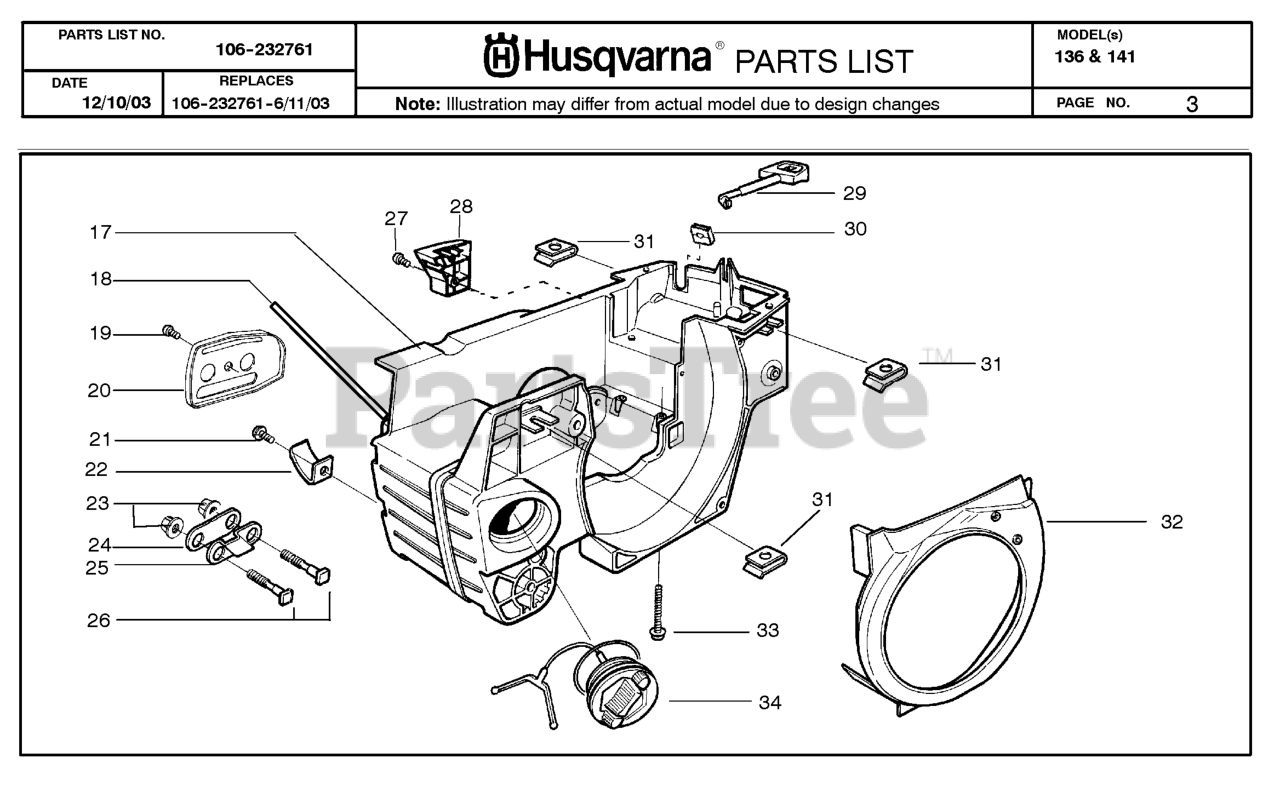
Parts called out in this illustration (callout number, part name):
4	SPUR SPRKT .325 7T 36/41
17	CRANKCASE ASSY
18	TUBE
22	CHAIN CATCHER 36/41
24	OIL TANK GASKET
25	PLATE,BAR MOUNT
26	BAR BOLT 36/41
28	LIMITER COVER
29	CHOKE 36/41
30	CHOKE GUIDE 36/41
32	AIR CONDUCTOR 36/41
33	SCREW M5-0.8X35M TAP
